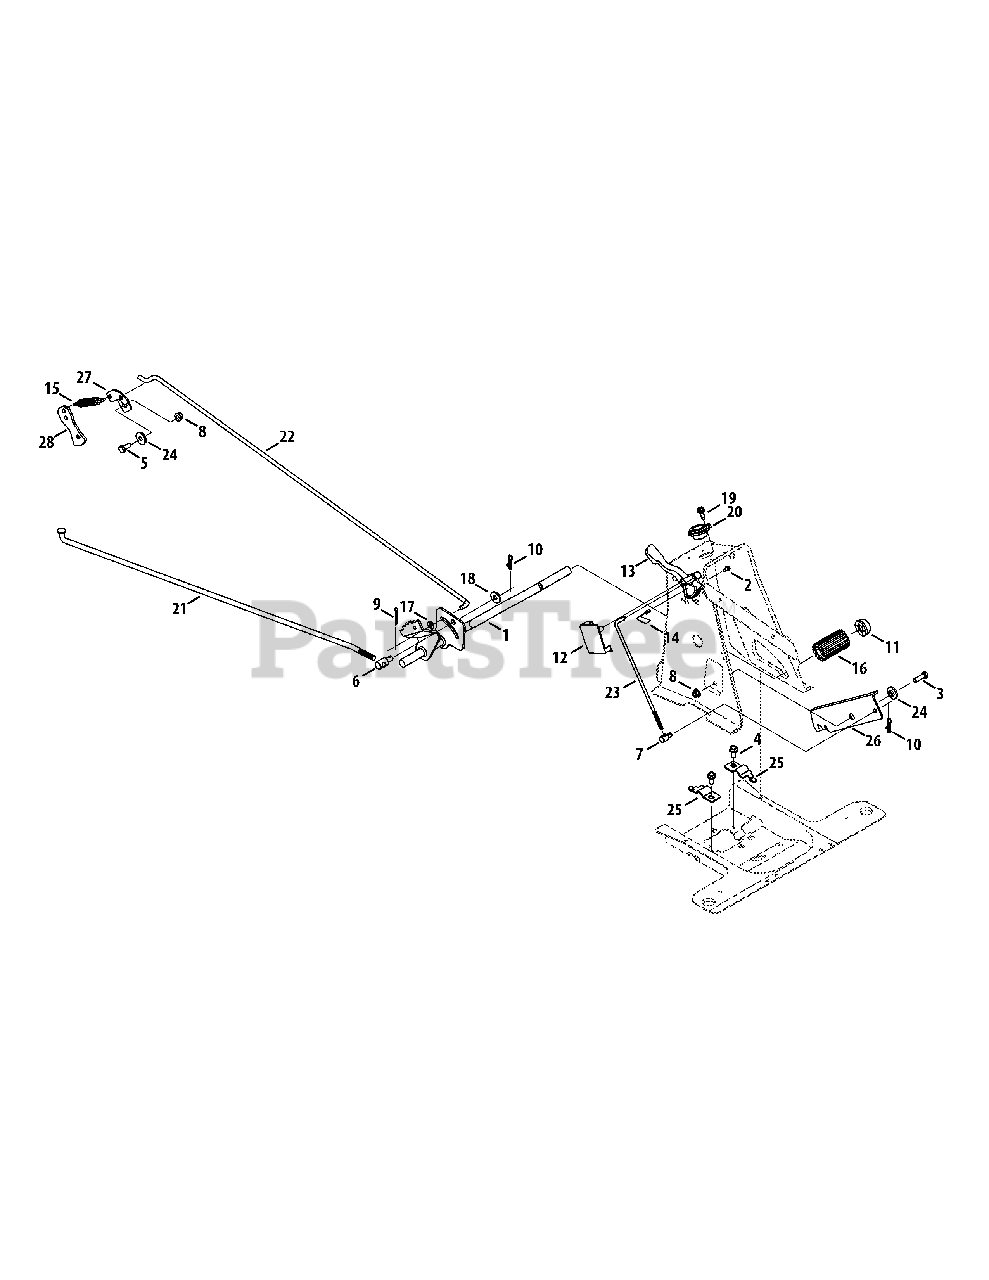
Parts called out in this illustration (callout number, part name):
1	Brake Pedal Assembly
2	Screw, #10-16x0.500
3	Hex Head Scerw, 5/16-18x1.00
4	Tap Screw, 5/16-18x.750
5	Hex Head Screw, 5/16-18x.75
6	Ferrule 3/8-24 X .375 Dia.
7	Adjustable Ferrule, 1/4-20 X 1.00
8	Flange Lock Nut, 5/16-18
9	Cotter Pin, 3/32X1.0
10	Bow-Tie Cotter Pin, 72
11	Push Cap, 5/8
12	Speed Control Cover
13	Speed Lever, 6-Speed
14	Shift Spring
15	Extension Spring, .59 OD X 4.00 LG
16	Foot Pad, 2.5" LG.
17	Flat Washer, .330x.630x.064
18	Flat Washer, .380X.930X.110
19	Shoulder Screw, .368 X.113, 1/4-20
20	Steering Col. Bearing, .880 ID X 1.36
21	Variable Speed Control Rod
22	Brake Rod
23	Speed Selector Control Rod
24	Shoulder Spacer
25	Pedal Strap Support Bracket, 5/8
26	Speed Latch Bracket
27	Brake Cam Bracket
28	Brake lever Bracket
